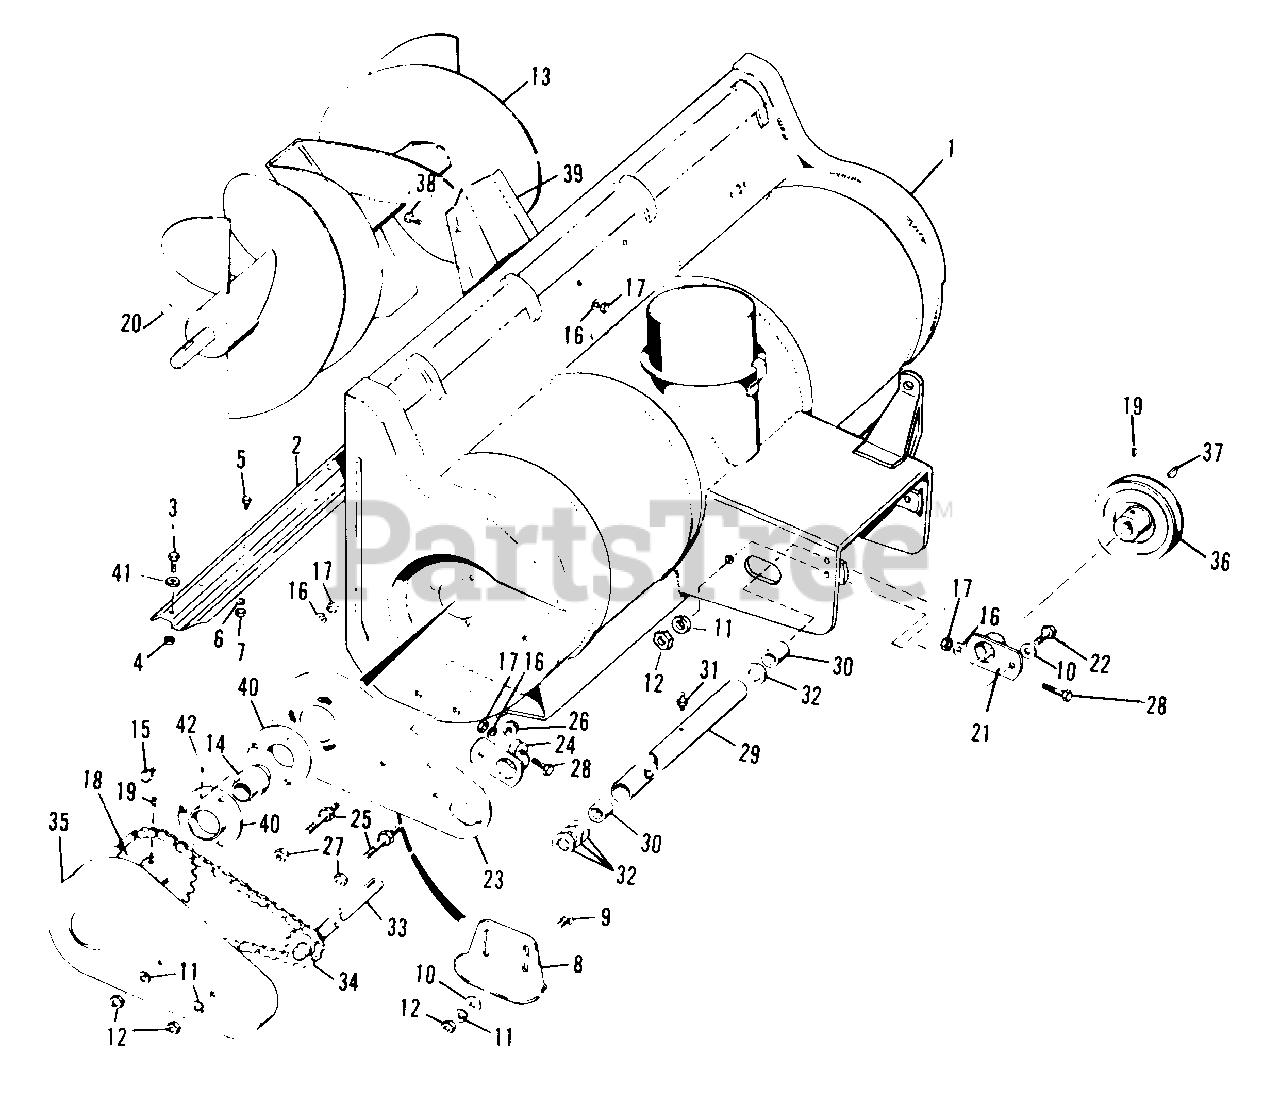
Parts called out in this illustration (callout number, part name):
1	BODY ASSEMBLY
2	SCRAPER BODY
3	CAPSCREW, Hex, 5/16-18 x 5/8
4	LOCKNUT, Full hex, 5/16-18
5	CAPSCREW, Hex, 1/4-20 x 5/8
6	LOCKWASHER, 1/4
7	NUT, Full hex, 1/4-20
9	BOLT, Carriage, 3/8-16 x 3/4
10	WASHER, Plain, 3/8
11	LOCKWASHER, 3/8
12	NUT, full hex, 3/8-16
13	ROTOR ASSEMBLY
14	BEARING, Cartridge
15	CAPSCREW, Hex,
16	LOCKWASHER, 5/16
17	NUT, Full hex
18	ROTOR, Sprocket
19	SETSCREW, 5/16-18 x 5/16
20	KEY, Hi-Pro
21	CLAMP SUPPORT ASSY.
22	CAPSCREW, Hex, 3/8-16 x 1
23	PLATE, Side
24	CLAMP SUPPORT ASSY.
26	NUT, Flange, 3/8-16
27	LOCKNUT, Full hex, 3/8-16
28	CAPSCREW, Hex, 5/16-18 x 1-1/2
29	BEARING, Housing
30	BEARING, Needle
31	FITTING, Grease
33	SHAFT ASSEMBLY
35	GUARD, Chain
37	KEY, 3/16 dia., x 3/4
38	CAPSCREW, Hex,
40	FLANGE, Bearing
